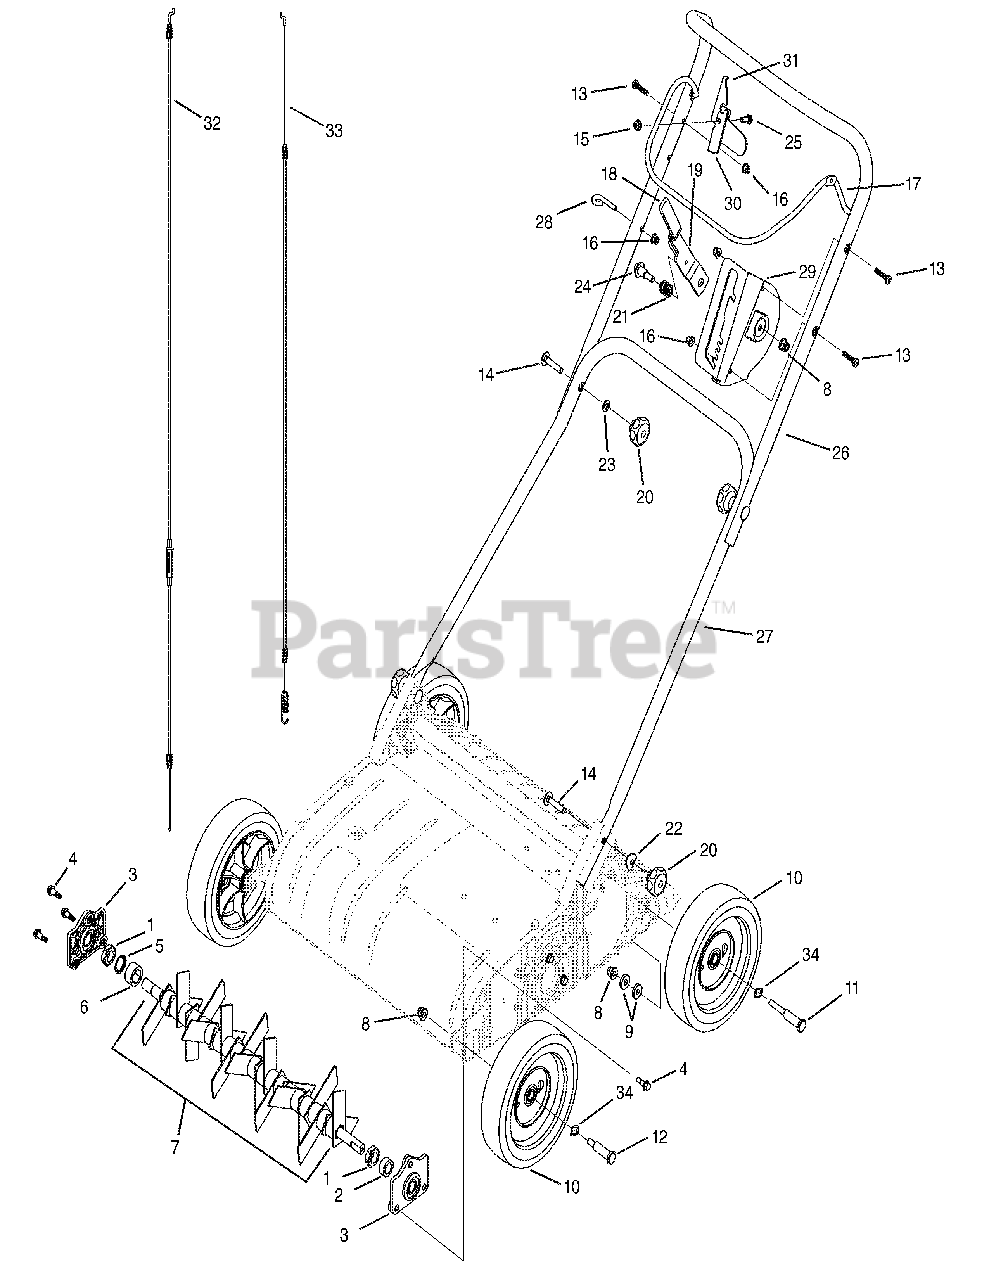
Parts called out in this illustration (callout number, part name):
1	Nut, M18 x 1.5
2	Bearing Spacer
3	Bearing Assembly
4	Should Screw, 7.13 x 11.5
5	Safety Washer
6	Hex Spacer Shaft
7	Blade Assembly
8	Flange Lock Nut, M8 - 1.25
9	Flat Washer, 8.20 x 20.93 x 4.00
10	Wheel, 8 x 2.125
11	Shoulder Screw, 12.63 x 37.98
12	Shoulder Screw, 12.63 x 37.98
13	Spacer, M6 - 1.30
14	Carrier Spacer, M8 - 1.25
15	Flange Lock Nut, 1/4 - 20
16	Flange Lock Nut, M6 - 1
18	Handle Grip
19	Height Adjustment Lift Handle
20	Turning Knob, M8 x 1.25
21	Compression Spacer, .087 x .715 x .688
22	Saddle Washer, .320 x .93 x .060
23	Flat Washer, 8.4 x 16 x 1.60
24	Shoulder Spacer, 11.87 x 15.5
25	Shoulder Bolt, .375 x .125
26	Upper Handle
27	Lower Handle
28	Eye Bolt
29	Height Adjustment Bracket Mount
30	Bail Interlock Bracket Mount
31	Bail Interlock Pivot Bracket
32	Clutch Cable
33	Height Cable Adjustment
34	Wave Washer
